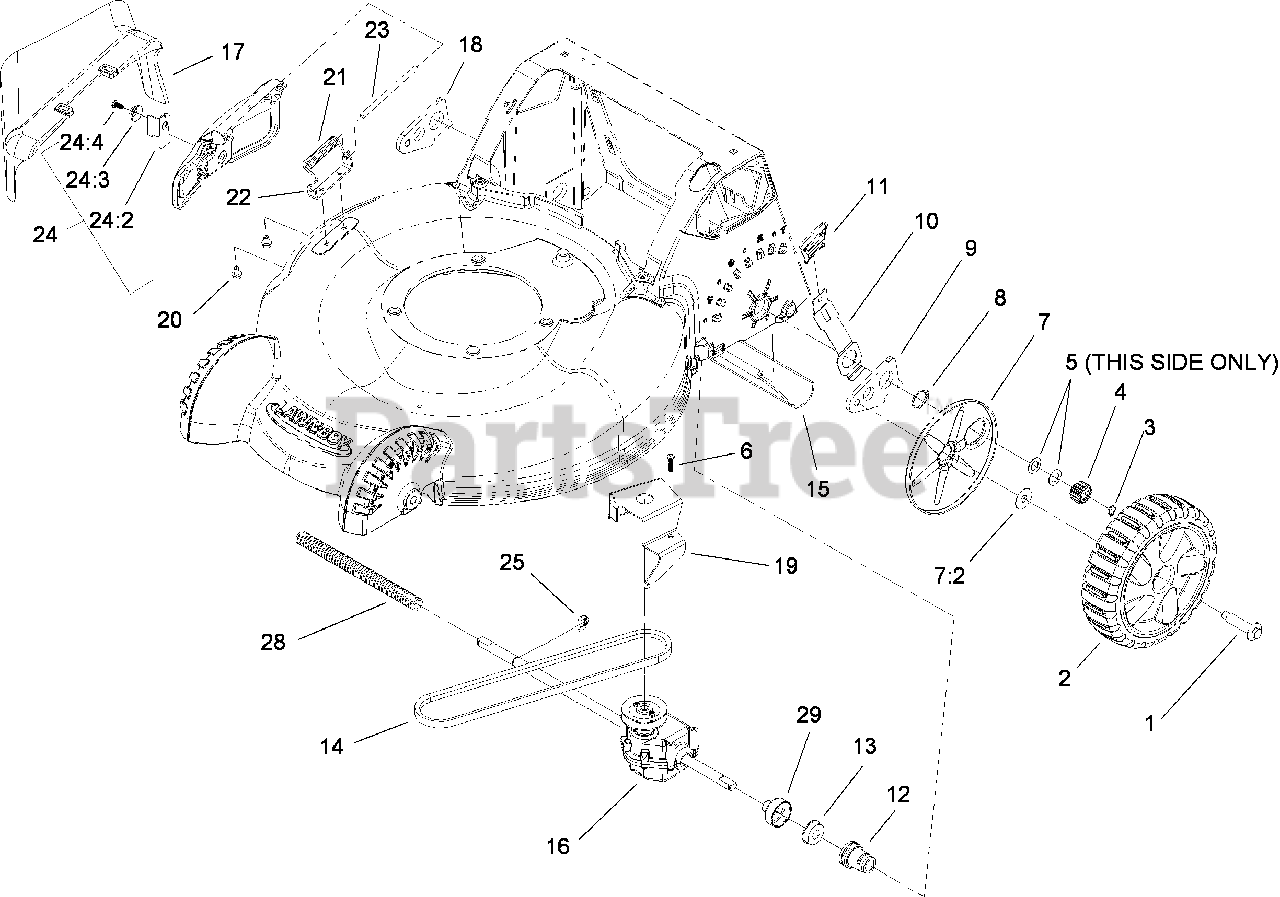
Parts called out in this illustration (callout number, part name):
1	BOLT-SHOULDER
2	REAR WHEEL ASM
3	RING-RETAINING
4	PINION
5	WASHER-PLAIN
6	SCREW-PLASTITE
7	WHEEL COVER ASM
7:2	WASHER-STEPPED
8	RING-RETAINING
9	ARM-REAR PIVOT, LH
10	ARM-SPRING, REAR
12	RETAINER-BEARING
13	BEARING-BALL
15	SHIELD-TRAILING
16	TRANSMISSION ASM
17	CHUTE-DISCHARGE, SIDE
18	ARM-REAR PIVOT, RH
19	BRACKET-TRANSMISSION
20	SCREW-HWH
21	SPRING-TORSION
22	BRACKET-COVER
23	ROD-COVER
24	DISCHARGE DOOR ASM
24:2	LATCH-DOOR
24:3	CAP-DOOR
24:4	SCREW-PLASTITE
25	RING-CLIP, LOCKING
28	COVER-SHAFT, DRIVE
29	CAP-BEARING
